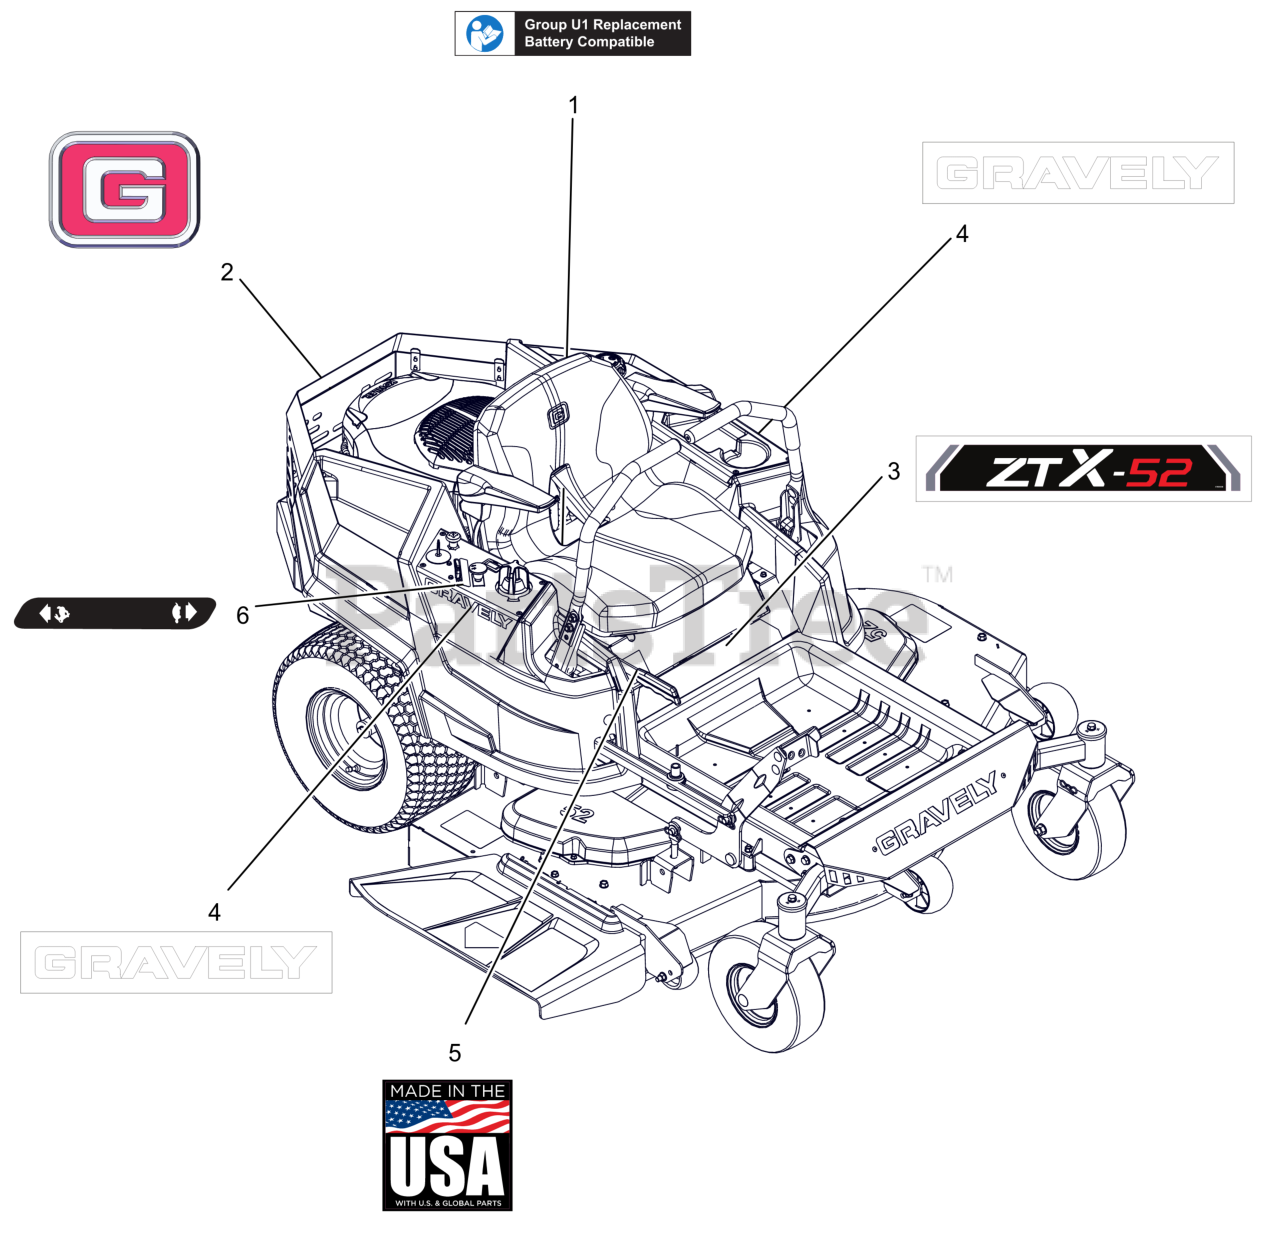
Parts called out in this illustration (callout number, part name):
1	DECAL, U1 BATTERY REPLACEMENT
2	DECAL, GRAVELY BRAND
3	DECAL, GRAVELY ZT X 52
4	DECAL, 9.5" GRAVELY LOGO
5	DECAL, MADE IN USA
6	DECAL, DASH DECAL
